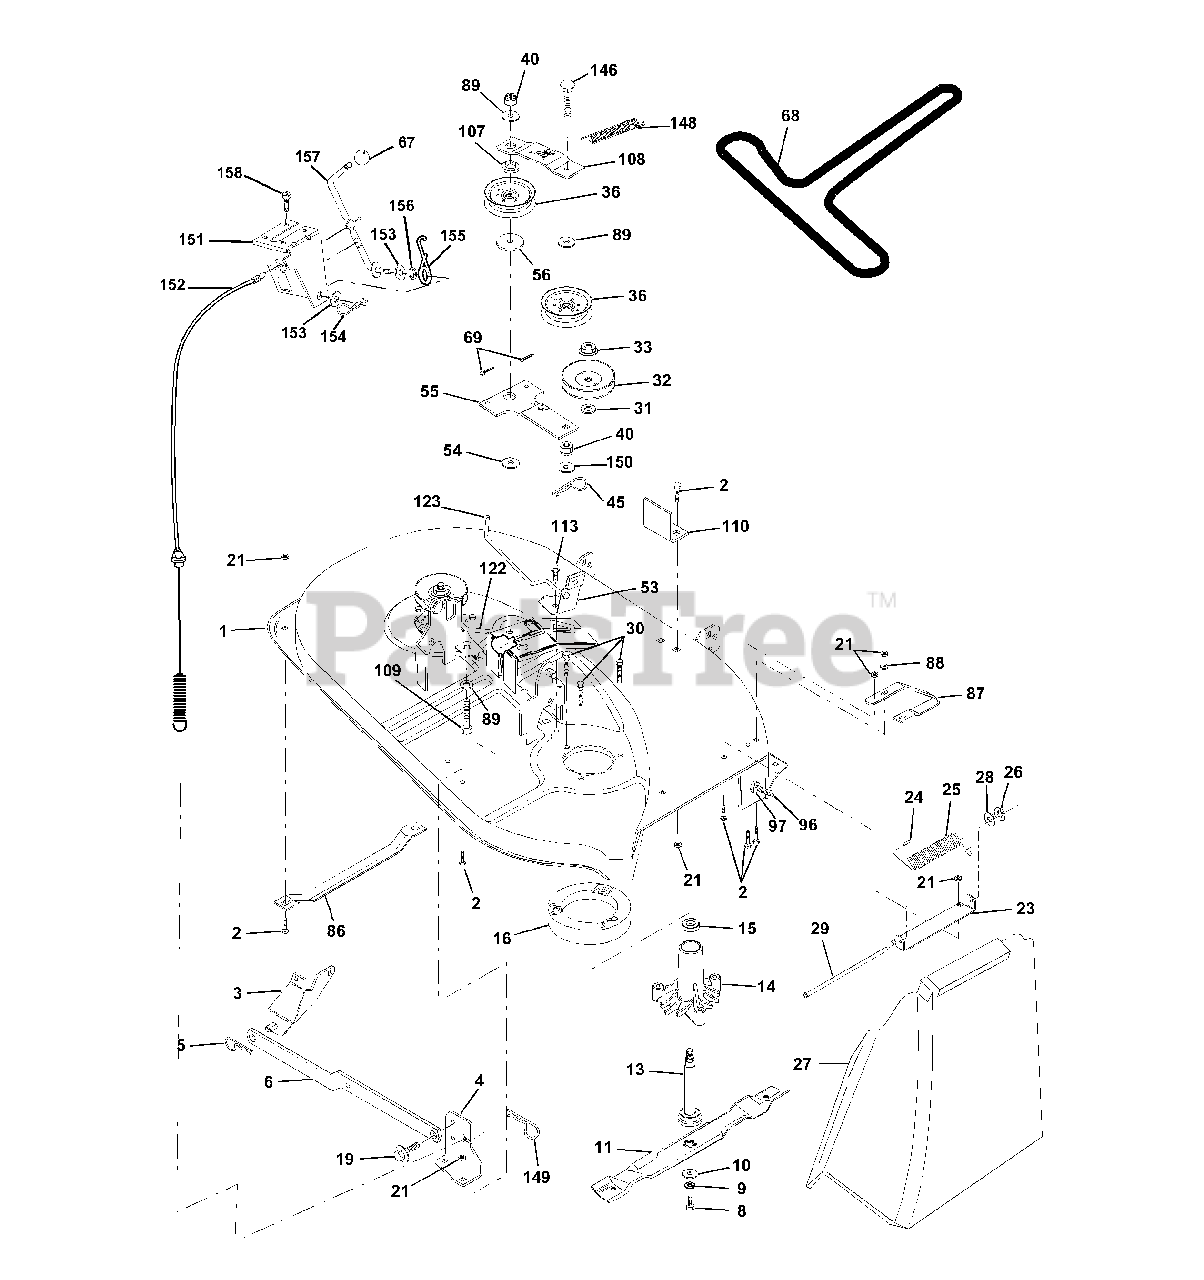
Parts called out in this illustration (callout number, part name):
1	Mower Housing Assembly
2	Bolt, Carriage 5/16-18 x 3/4
3	Bracket Asm. Fram Sway Bar
4	Bracket, Asm. Deck Sway Bar
5	Retainer, Spring
6	Asm. Suspension Rear
8	Bolt, Hex 3/8-24 x 1-1/4 Gr 8
9	Washer, Lock, Hlcl Sprg 3/8
10	Washer, Hard Blade Mower Vented
11	Blade, Mower, Mulching 38"
13	Shaft and Bearing Assembly
14	Mandrel Housing, Vented
15	Ball Bearing, Mandrel
16	Stripper, Mower, Vented
19	Bolt, Shoulder
21	Nut, Crownlock 5/16-18
23	Bracket, Mower Deflector
24	Cap, Sleeve
25	Spring, Deflector
26	Nut, Push
27	Shield, Deflector
28	Washer 11/32 x 3/4 x 16 Ga
29	Rod, Hinge
30	Screw, Thdro Washer Hd
31	Washer, Spacer
32	Pulley, Mandrel
33	Nut, Flangelock 9/16
36	Pulley, Idler, Flat
40	Nut Crownlock 3/8-16
45	Retainer, Spring
53	Brake Assembly
54	Washer Hardened
55	Idler Arm Assembly
56	Spacer, Retainer
67	Knob
68	Belt
69	Pin, Cotter 3/32 x 3/4
86	Runner, LH
87	Runner, RH
88	Washer 11/32 x 3/4 x 16 Ga
89	Washer 13/32 x 1 x 12 Ga
96	Bolt 3/8-16 x 1-1/4
97	Nut Centerlock 3/8-16
107	Spacer, Retainer
108	Stiffener, Idler Arm
109	Bolt, Hex Head 3/8-16 x2-1/2
110	Upstop Deck Front 38"
113	Screw 5/16-18 x 3/4
122	Rod, Brake, LH
123	Rod, Brake, RH
146	Bolt Carriage Idler
148	Spring Return Idler
149	Retainer Spring Yellow Zinc
150	Washer 9/32 x 3/4 x 16 Ga.
151	Bracket Clutch
152	Cable Clutch 38 In
153	Washer Flat 3/8" Type B
154	Spring Retainer
155	Spring Retention Lever
156	Spacer
157	Rod Clutch
158	Screw Hex Thd Cut 1/4-20x5/8
